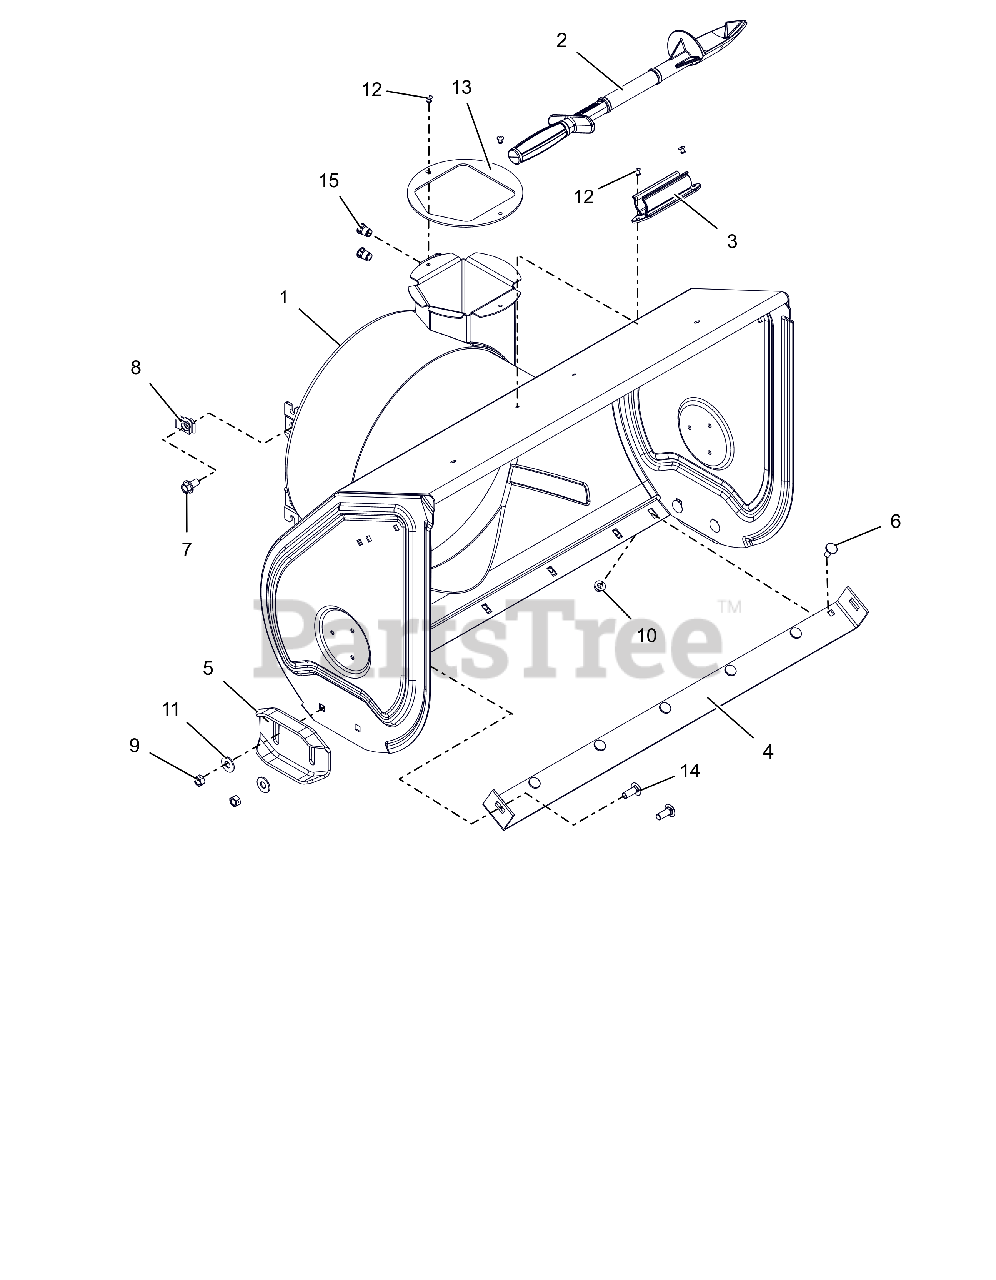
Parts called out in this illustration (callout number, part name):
1	BLOWER HOUSING W/DECAL 30"
2	DEVICE, SNOW CLEAN OUT
3	MOUNT, SNOW CLEAN OUT
4	BLADE, SCRAPER-30"
5	SKID SHOE, REVERSIBLE - ORANGE
6	BOLT, MODIFIED HEAD CARRIAGE
7	BLT-SERHFWH .38-16X.75 YWZC
8	NUT-RTNR .375-16X.37
9	@NUT-LK-CTR .38-16 YWZC
10	@NUT-LK-TOP-FLG .31-18 YWZC
11	@WSHR-FL-STL.438X1.00X.083 YWZ
12	RVT-POP .187 YZ
13	BAFFLE, DISCHARGE NECK
14	@BLT-RDHDSHSQNK.38-16X1.0 G5YZ
15	NUT, THREADED INSERT .38-16
